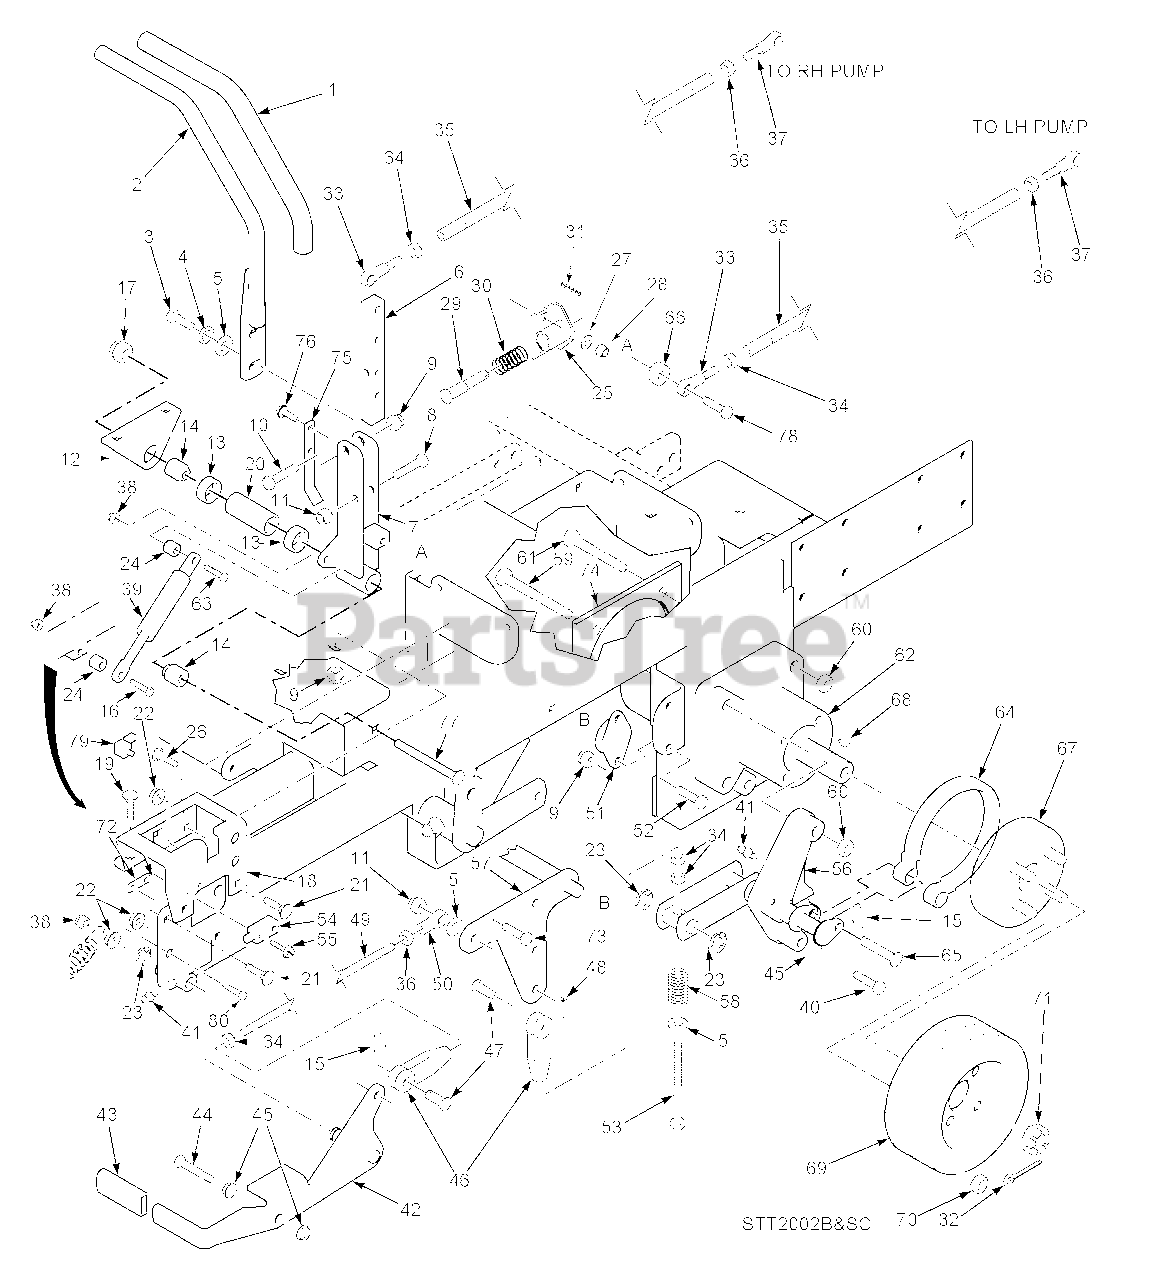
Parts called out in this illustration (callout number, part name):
1	Grip, Handle Bar
2	Handle Bar
3	Bolt, Hex Head 3/8-16 x 1-1/4"
4	Lockwasher, 3/8"
5	Flatwasher. 3/8" (.391 x .938 x .105)
6	Bar, Control Lever
7	Control Lever Weldment, LH
8	Bolt, Hex Head 5/16-18 x 2"
9	Nut, Hex Elastic Stop 5/16-18
10	Bolt, Hex Head 3/8-16 x 2"
11	Nut, Hex Elastic Stop
12	Mount, Control Linkage
13	Ball Bearings, Neutral Return
14	Spacer
15	Pin, Rue Cotter 3/8 Dia.
16	Bolt, Hex Head, 5/16-18 x 2.75 Zinc.
17	Nut, Hex Elastic Stop 5/8-11
18	Bracket, Control Lever LH
19	Bolt, Carriage 5/16-18 x 1"
20	Spacer, Bearing
21	Bolt, Carriage 5/16-18 x 3/4"
22	Nut, Hex Serrated Flange 5/16-18
23	Ring, Retaining 5/8" External "E"
24	Spacer
25	Bracket, Neutral Return
26	Bolt, Carriage 1/4-20 x 3/4"
27	Flatwasher, 1/4" (.312 x .750 x .065)
28	Nut, Hex Elastic Stop 1/4-20
29	Pin, Retaining Spring
30	Spring
31	Roll Pin, Spring 5/32 x 3/4"
32	Pin, Cotter 9/16 x 1-1/2"
33	Rod End, Male 3/8-24 RH Thread
34	Nut, 3/8-24 RH Thread
35	Tube, Control Link Air Cooled Engine
36	Nut, Hex 3/8-24 LH Thread
37	Rod End, Male 3/8-24 LH Thread
38	Locknut, 5/16-18, Elastic Stop
39	Gas Damper
40	Bolt, Hex Head 3/8-16 x 2-1/2"
41	Grease Fitting
42	Lever, Parking Brake
43	Grip, Parking Brake
44	Bolt, Hex Head 3/8-16 x 2-3/4"
45	Nut, Hex Serrated Flange 3/8-16
46	Clevis, Traction Control
47	Pin, Clevis 3/8-16 x 1-1/16"
48	Pin, Cotter 3/32 x .75
49	Rod, Parking Brake
50	Rod End, LH Thread
51	Bushing, Self Align
52	Bolt, Hex Head 5/16-18 x 3/4"
53	Bolt, Hex Hd 3/8-24 x 5-1/4", 23/4" Thrd
54	Switch
55	Screw, Hex SLTD WSHR Head #10 32 x 3/4"
56	Brake Linkage, LH
57	Bellcrank, Brake Actuator
58	Spring
59	Bolt, Hex Head 1/2-13 x 3-3/4"
60	Locknut, Hex 1/2-13 Center Lock
61	Bolt, Hex Head 1/2-13 x 2-1/2"
62	Wheel Motor, Ross
63	Bolt, Hex Head, 5/16-18 x 1.75, Zinc
64	Brake Band Assembly
65	Pin, Clevis 3/8" Dia. x 1.93"
66	Spacer
67	Wheel Hub/Brake Drum Assembly
68	Key, Woodruff 5/16 x 1"
69	Wheel Assembly 23 x 10.5-12
70	Lug Nut, 1/2-20
71	Nut, Hex Castle
72	Threaded Plate
73	Bolt, Hex Head 3/8-16 x 1-1/2"
74	Plate Weldment, Motor Backing
75	Actuator Switch
76	Bolt, Hex Serrated Flange 5/16-18 x 3/4"
77	Bolt, Carriage 3/8-16 x 4-3/4"
78	Bolt, Hex Head 3/8-16 x 1"
79	Switch
80	Bolt, Hex Head 3/8-16 x 1-1/4" Grade 8
